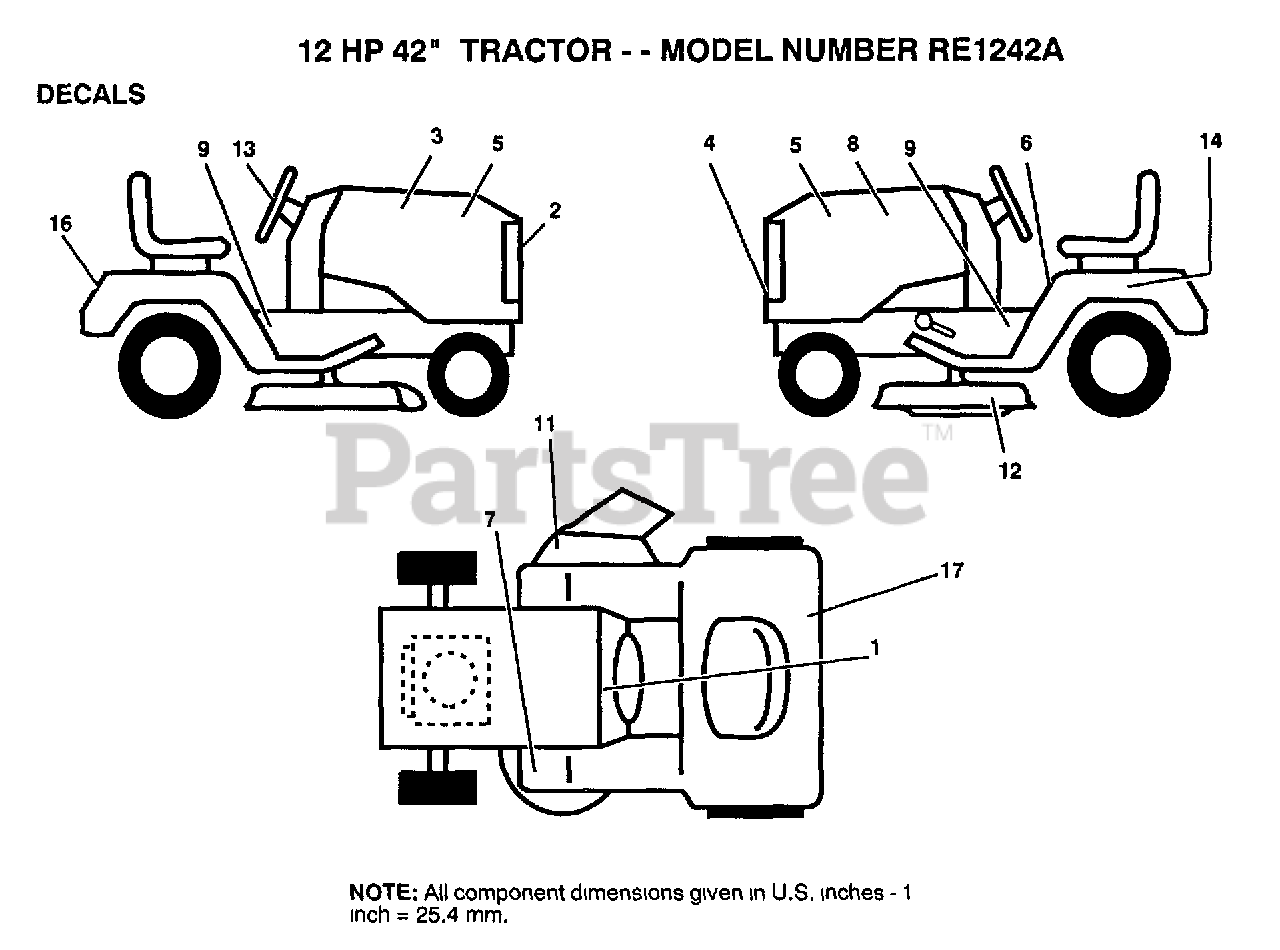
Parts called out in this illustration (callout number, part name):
2	GRILL DECAL
5	"DECAL,HOOD"
6	DECAL CAUTION
7	DECAL T
9	CHASSIS DECAL
11	DECAL WARNING
12	DECAL YT
13	"DECAL,STR WHL"
14	DECAL
16	FENDER DECAL
